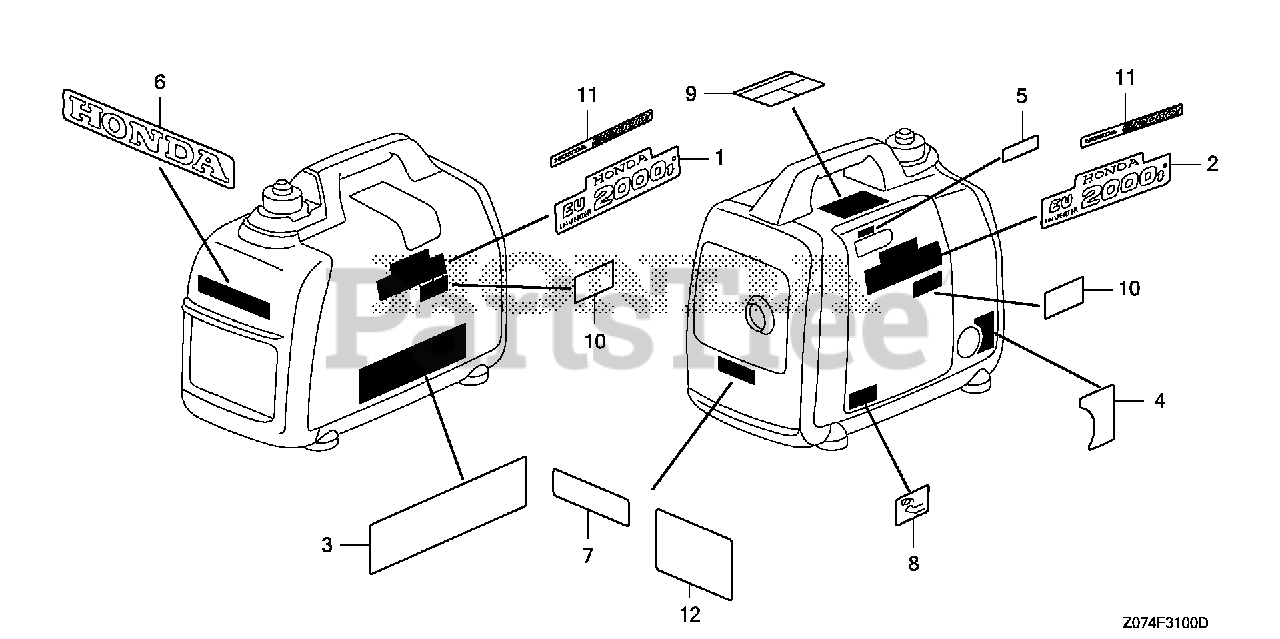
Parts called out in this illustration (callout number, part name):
1	MARK, EMBLEM
1	MARK, EMBLEM (EU2000I)
2	MARK, EMBLEM (EU2000I)
3	MARK, CAUTION
4	MARK, ENGINE SWITCH
5	MARK, CHOKE
6	MARK, HONDA
7	MARK, EX. CAUTION
8	MARK, OIL CAUTION
9	MARK, CPSC (CO CAUTION)
